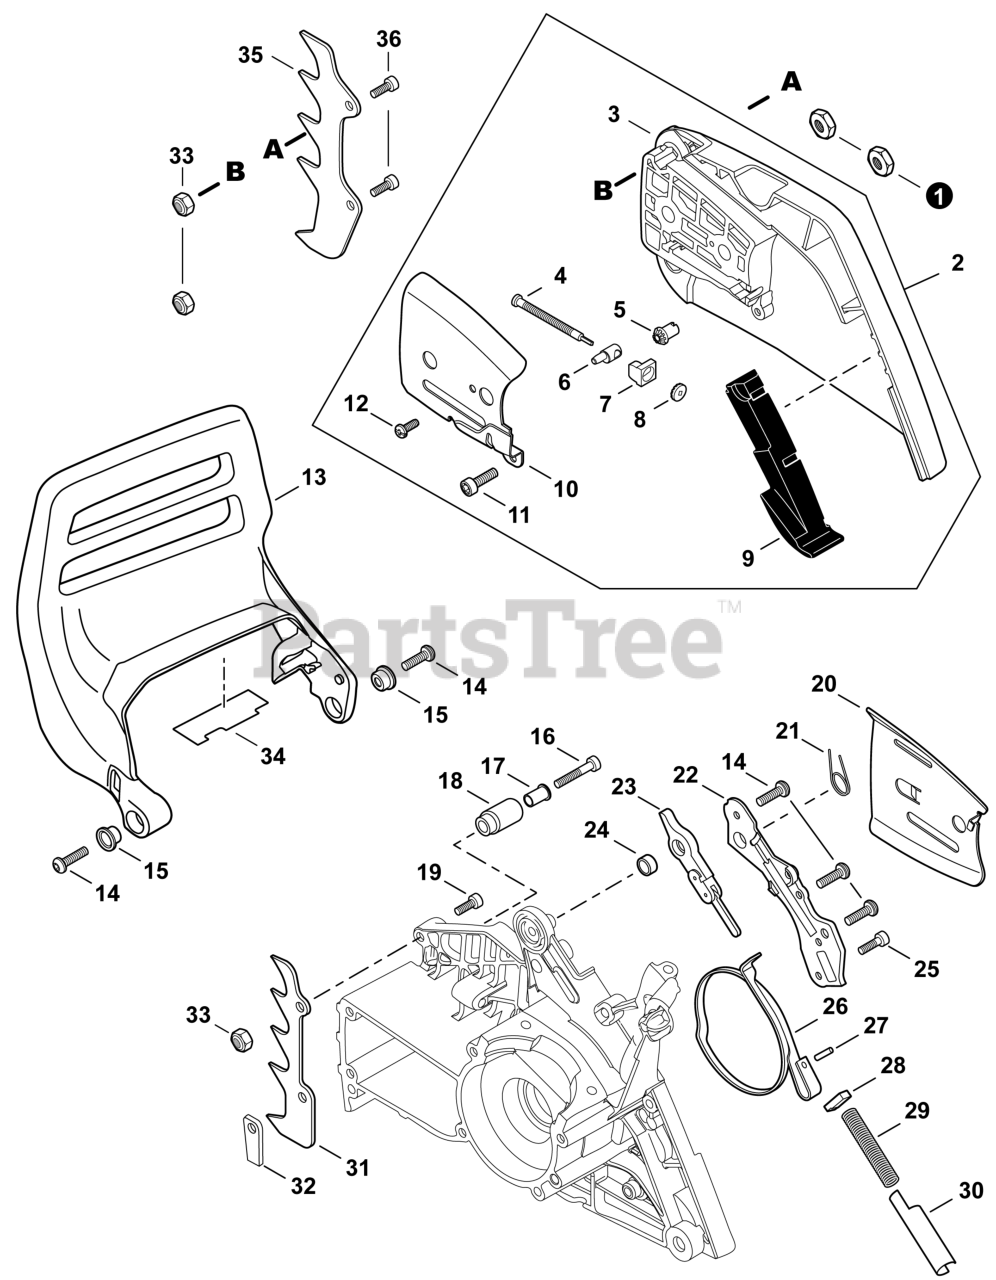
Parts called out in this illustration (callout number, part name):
2	SPROCKET GUARD ASSY
3	GUARD, SPROCKET
4	SCREW, CHAIN TENSION 63 MM
5	GEAR, BEVEL
6	TENSIONER, CHAIN
7	COLLAR 8
8	GEAR, BEVEL
9	CUSHION
10	PLATE, GUIDE - OUTER
11	BOLT, TORX 4×12
12	SCREW 3×5
13	LEVER, BRAKE
14	BOLT, TORX 5×16
15	COLLAR 11.2×16.2×T0.6
16	BOLT, TORX 5×35
17	COLLAR 5
18	CHAIN CATCHER
19	BOLT, TORX 5×16
20	PLATE, GUIDE - INNER
21	SPRING, TORSION
22	COVER, BRAKE
23	CONNECTOR, BRAKE
24	SPACER 12×10×T: 1.0
25	BOLT, TORX 4×12
26	BAND, BRAKE
27	PIN, SPRING 3×9.8
29	SPRING, COMPRESSION Ø12×70.5
30	PLATE, SIDE
31	SPIKE, BUMPER
33	NUT, LOCK M5
34	SHIELD, HEAT 75×27×0.15
35	SPIKE, BUMPER
36	BOLT, TORX 5×12
